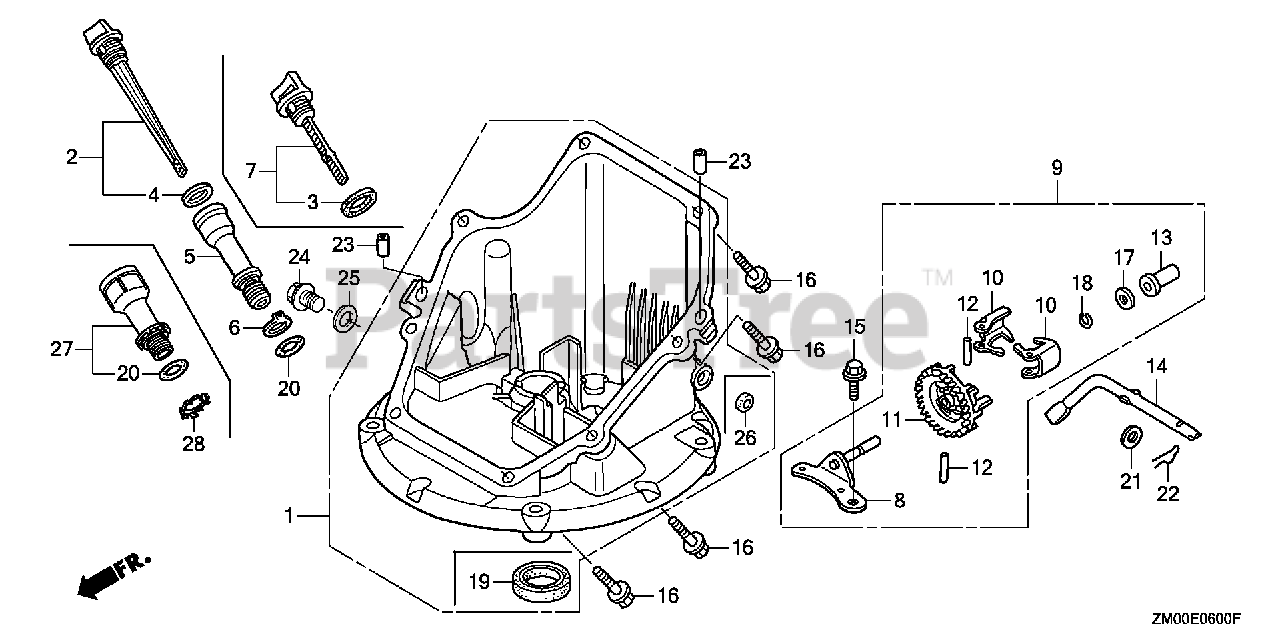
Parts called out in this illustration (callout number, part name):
1	PAN ASSY., OIL
3	GASKET, OIL FILLER CAP (NOT AVAILABLE)
7	GAUGE ASSY., OIL LEVEL
8	SHAFT, GOVERNOR HOLDER
9	GOVERNOR ASSY.
10	WEIGHT, GOVERNOR
11	HOLDER, GOVERNOR WEIGHT
12	PIN, GOVERNOR WEIGHT
13	SLIDER, GOVERNOR
14	SHAFT, GOVERNOR ARM
15	BOLT, FLANGE (6X14)
16	BOLT, FLANGE (6X25) Use up to Engine SN 2056819.
17	WASHER, THRUST (6MM)
18	CLIP, GOVERNOR HOLDER
19	OIL SEAL (28X41.25X6)
21	WASHER, PLAIN (6MM)
22	PIN, LOCK (8MM)
23	PIN, DOWEL (8X20)
